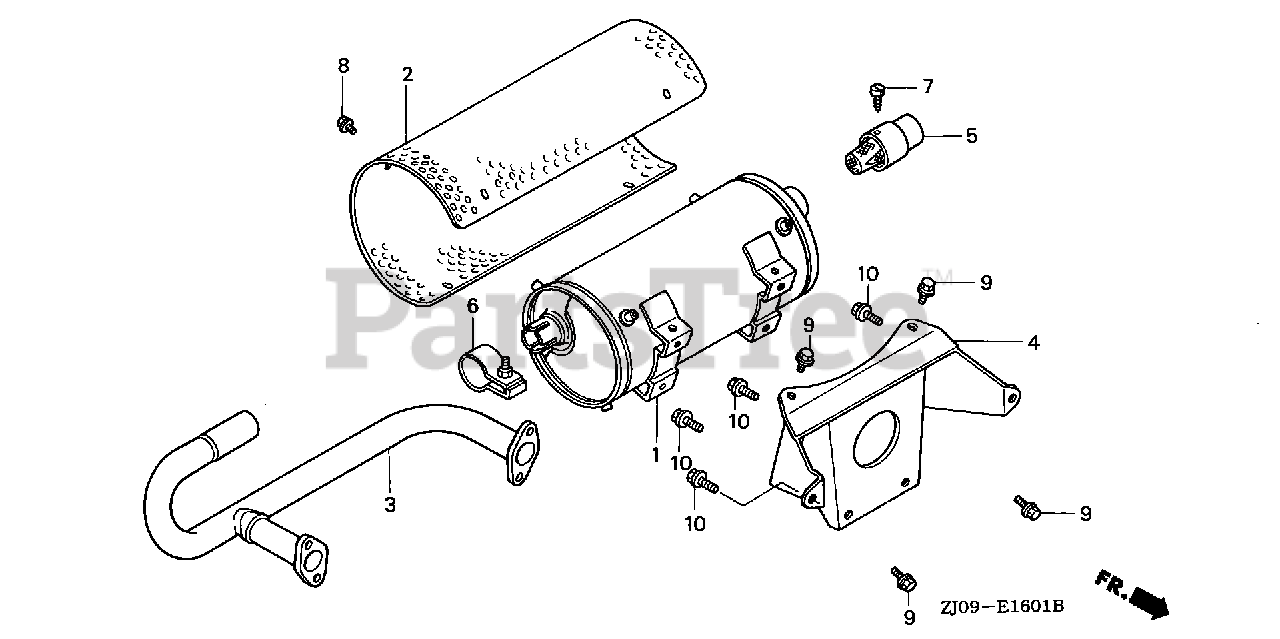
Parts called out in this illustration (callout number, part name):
1	MUFFLER (HIGH)
2	PROTECTOR, MUFFLER (HIGH)
3	PIPE, EX. (HIGH-L)
4	STAY, MUFFLER (HIGH)
5	ARRESTER, SPARK
6	BAND ASSY.
7	SCREW (NELSON)
8	BOLT, FLANGE (6X8)
9	BOLT, FLANGE (8X14)
10	BOLT, FLANGE (8X20)
